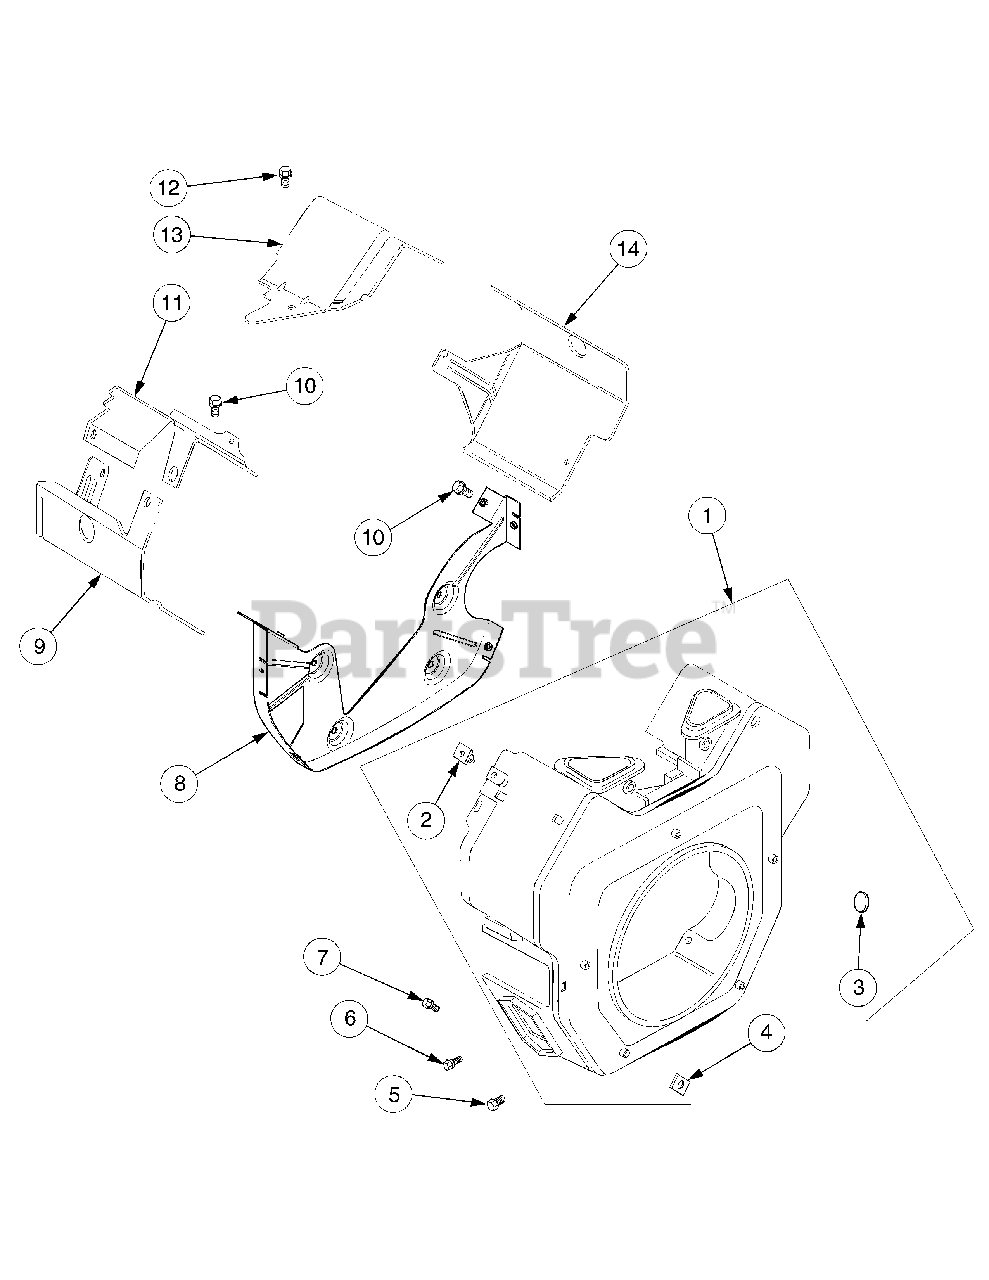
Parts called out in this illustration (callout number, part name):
1	Housing, Blower (Incl. Ref #2-4)
2	Nut, Plastic
3	Plug, Button, 9/16
4	Nut, Plastic
5	Screw, Hex Flange, M5 x 0.8 x 16
6	Screw, Hex Flange, M5 x 0.8 x 16
7	Screw, Hex Flange, M5 x 0.8 x 20
8	Plate, Backing
9	Baffle, Cylinder Barrel - #2 Side
10	Screw, Hex Flange, M6 x 1.0 x 16
11	Baffle, Valley - #2 Side
12	Screw, Hex Flange, M5 x 0.8 x 10
13	Baffle, Valley - #1 Side
14	Baffle, Cylinder Barrel - #1 Side
